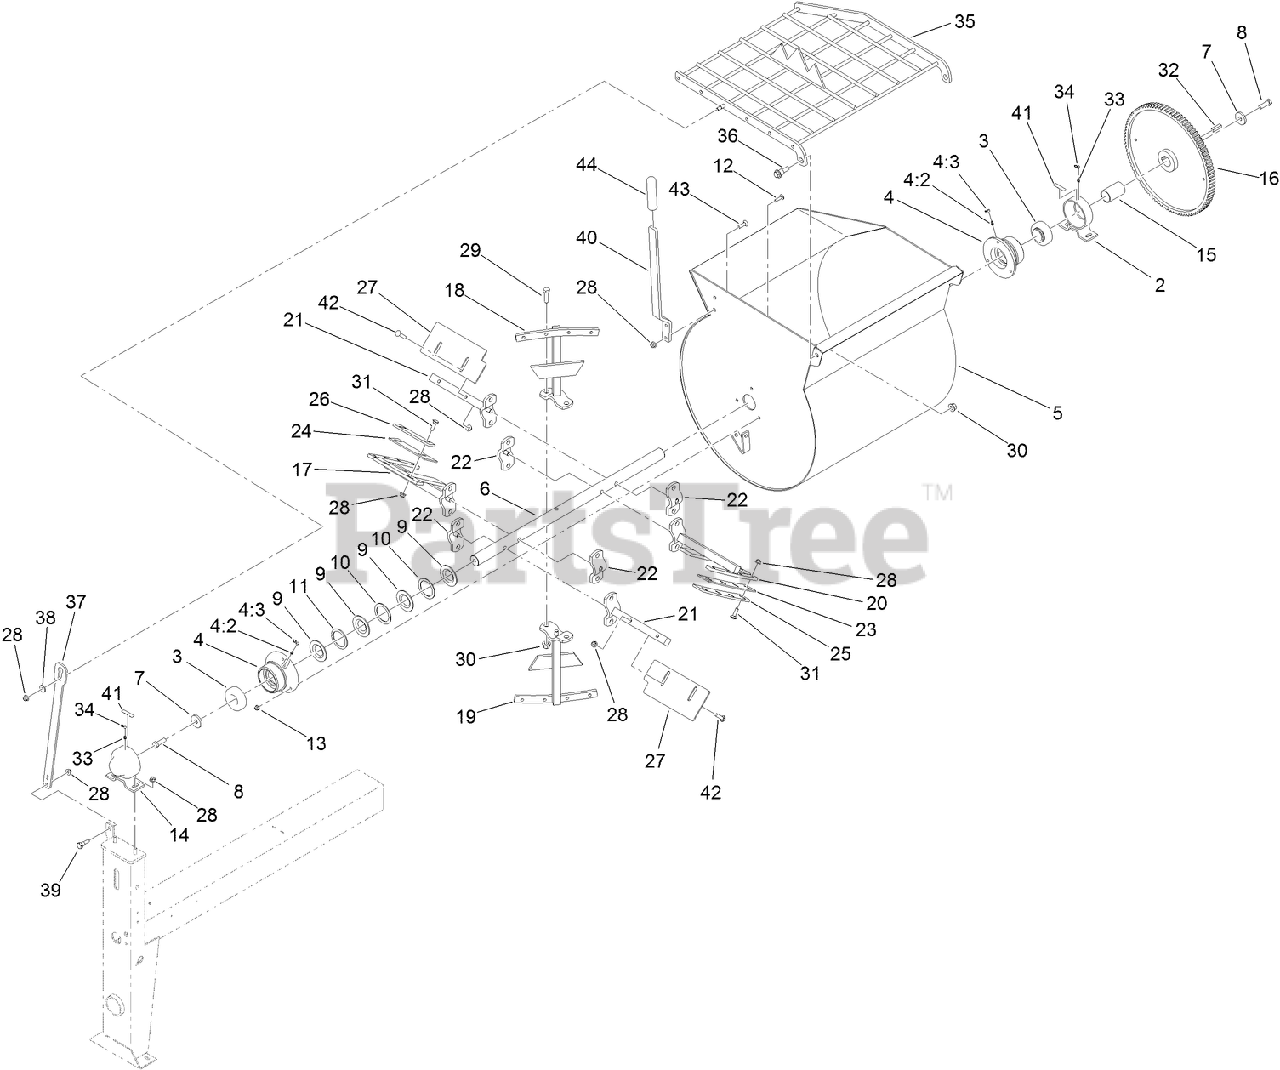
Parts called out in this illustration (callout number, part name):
2	TRUNNION
3	BEARING-BALL
4	KIT-HOUSING, BEARING
4:2	FITTING-GREASE
4:3	CAP-PLUG
6	SHAFT-PADDLE
7	WASHER-FLAT
8	SCREW-HH
9	SEAL-DRUM
10	WASHER-FLAT
11	WASHER-SPLIT
12	SCREW-CARR
13	NUT-HF, NI
14	TRUNNION-CAPPED
15	SPACER-SHAFT
16	GEAR-94 TEETH
17	PADDLE-FRONT
18	PADDLE-MID
19	PADDLE-MID
20	PADDLE-REAR
21	PADDLE-PUSHER
23	BLADE-RUBBER, TOP
24	PADDLE-RUBBER, MIXER END
25	PLATE-BACKER, TOP
26	BAR-BACKER, END
27	BAR-BACKER, PUSHER END
28	NUT-HF, NI
29	SCREW-HH
30	NUT-LOCK
31	BOLT-CARR
32	KEY-SQUARE
33	FITTING-GREASE
34	CAP-PLUG
36	SCREW-SHOULDER, HHF
37	ARM-LIFT, GRATE
38	WASHER-HARDENED
39	BOLT-SHOULDER
40	HANDLE-DUMP
41	DECAL-GREASE
42	SCREW-CARR
43	SCREW-CARR
44	GRIP-FOAM
